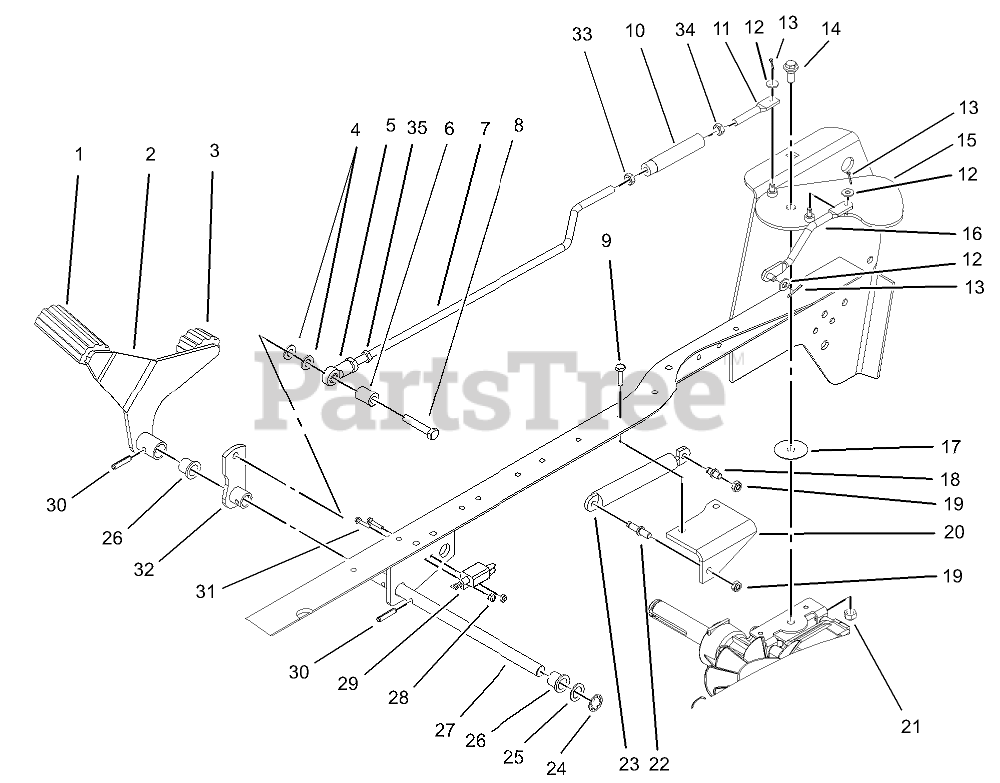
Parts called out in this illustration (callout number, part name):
1	PAD-PEDAL
2	HYDRO PEDAL ASM,
3	PAD-PEDAL
4	WASHER-FLAT
5	END-ROD, FEMALE
6	TUBE-INTERLOCK
7	ROD-HYDRO
8	SCREW-HH
9	SCREW-HWHTF
10	TURNBUCKLE
11	LINK-HYDRO
12	WASHER-PLAIN
13	PIN-COTTER
14	BOLT-SHOULDER
15	CRUISE PLATE ASM
16	BELL CRANK ROD ASM
17	SPACER-CRUISE
18	ARM-CONTROL, PIN DAMPER
19	NUT-LOCK, NI
20	BRACKET-DAMPER
22	PIN-BRACKET, DAMPER
23	DAMPER-GAS
24	RING-RETAINING
25	WASHER-FLAT
26	BUSHING-FLANGE
27	SHAFT-PIVOT, HYDRO
28	NUT-LOCK
29	SWITCH-ADJUSTABLE
30	PIN-SPRING
31	SCREW-SHWH
32	HYDRO LINK ASM
33	NUT-HJ
34	NUT-JAM
35	NUT-JAM
